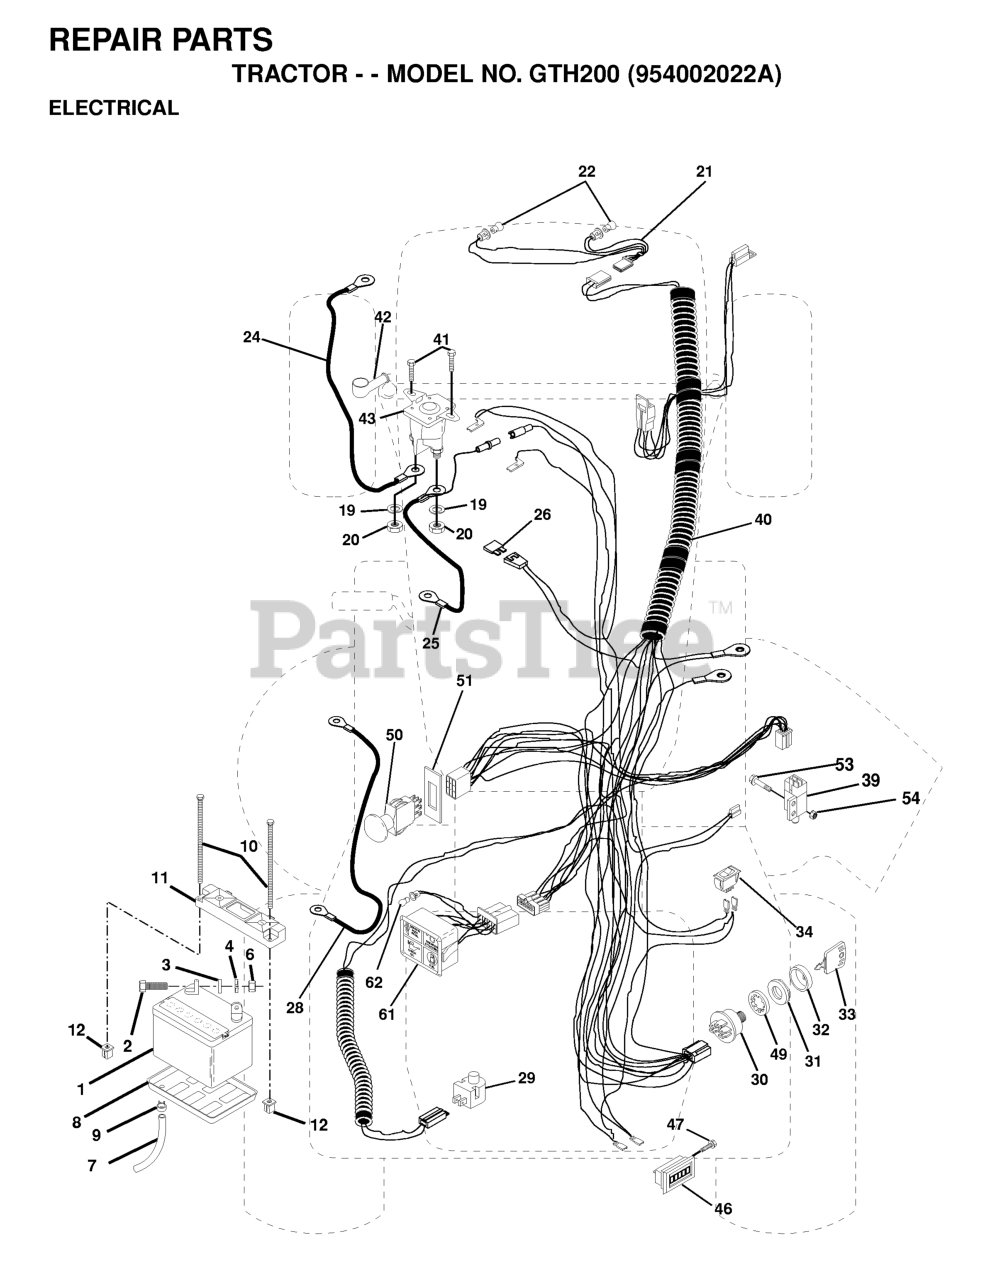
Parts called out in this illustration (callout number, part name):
1	BATTERY 12V .35 AMP
2	BOLT.HEX.1/4.X.3/4.DICHROMATE
3	LOCKWASHER
6	NUT
7	PLASTIC TUBE
8	BATTERY TRAY T
9	HOSE CLAMP T
10	BOLT 1/4-20 X 7.5
11	HOLDDOWN, BATTERY, DASH MOUNT
12	NUT, PUSH NYLON 1/4" BATTERY
19	LOCKWASHER
20	NUT
21	HARNESS LIGHT SOCKET
24	CABLE, STARTER
25	CABLE, BATTERY
28	CABLE, GROUND
29	RP.SWITCH.PLUNGER.NC.GRAY
30	IGNITION SWITCH
31	NUT, IGNITION
32	COVER SWITCH KEY
33	KEY MLD GEN DELTA
39	SWITCH INTERLOCKT
40	HARNESS, IGNITION
41	SCREW
42	TERMINAL COVER
43	SOLINOID
46	HOUR METER T
47	Screw 10-24 x 1/2 Black
49	Washer, Lock Internal Tooth 5/8
50	SWITCH-PTO
51	FRAME RETAINING RING
53	SCREW **
54	Nut, Hex, Keps #10-32 UNF
61	LIGHT PACKAGE
62	BULB LIGHT T
